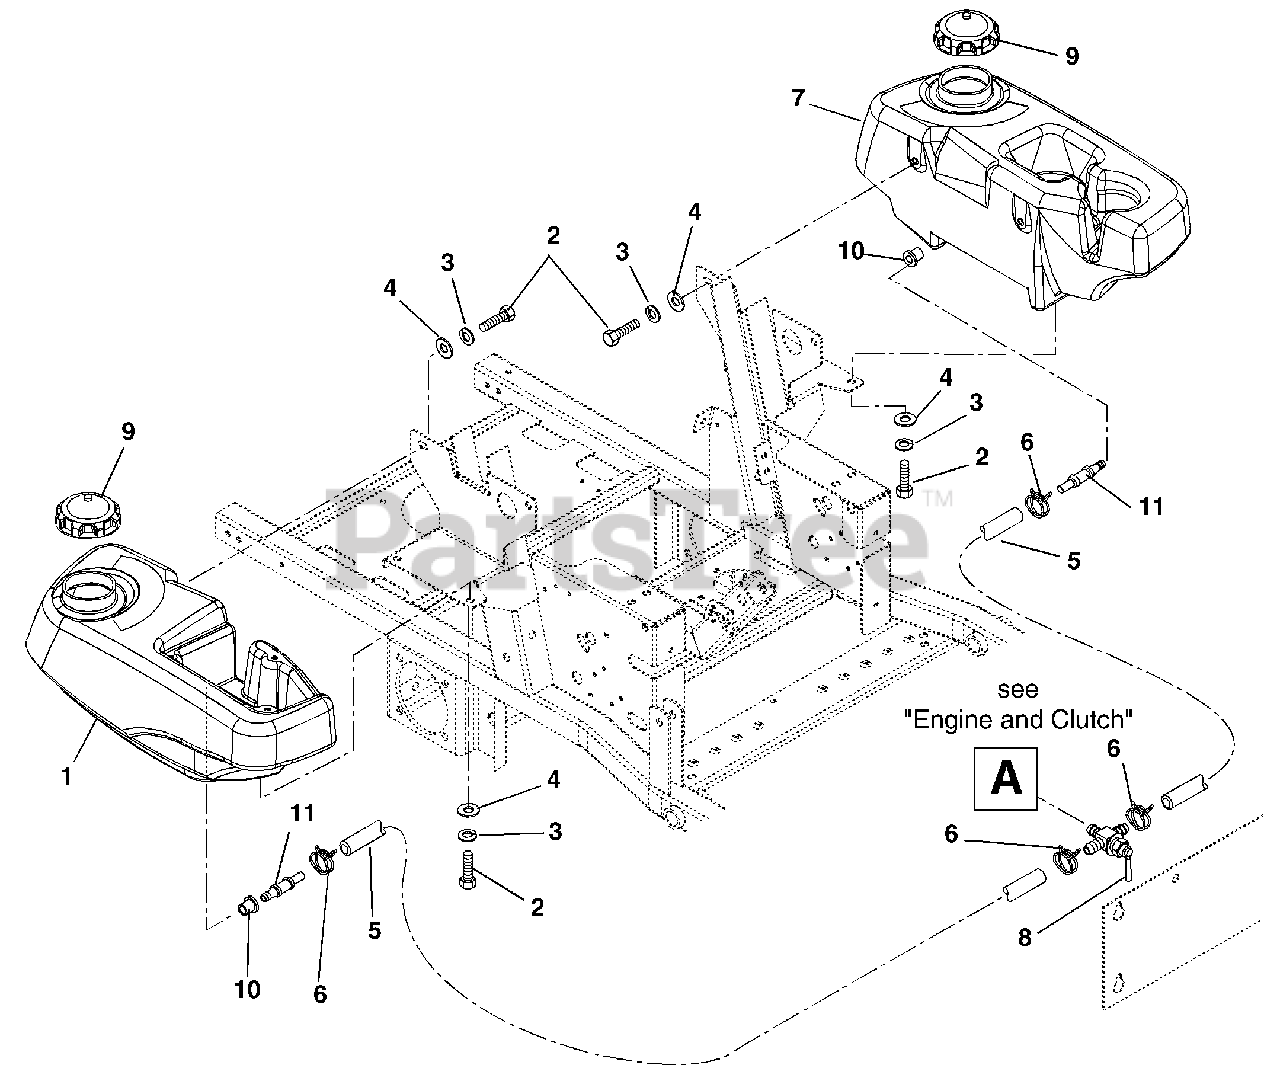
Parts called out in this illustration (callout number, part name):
1	Fuel Tank Right-Hand
2	Bolt-Hex .31-18 x .75 Grade 5
3	Washer-Locking .31 x .078
4	Washer-Flat-Steel .38 x .875 x .083
5	Gas Line-Bulk 1/4" ID
6	Hose-Clamp
7	Fuel Tank Left-Hand
8	Valve, Fuel
9	Cap-Gas
11	Fuel Tank Fitting
